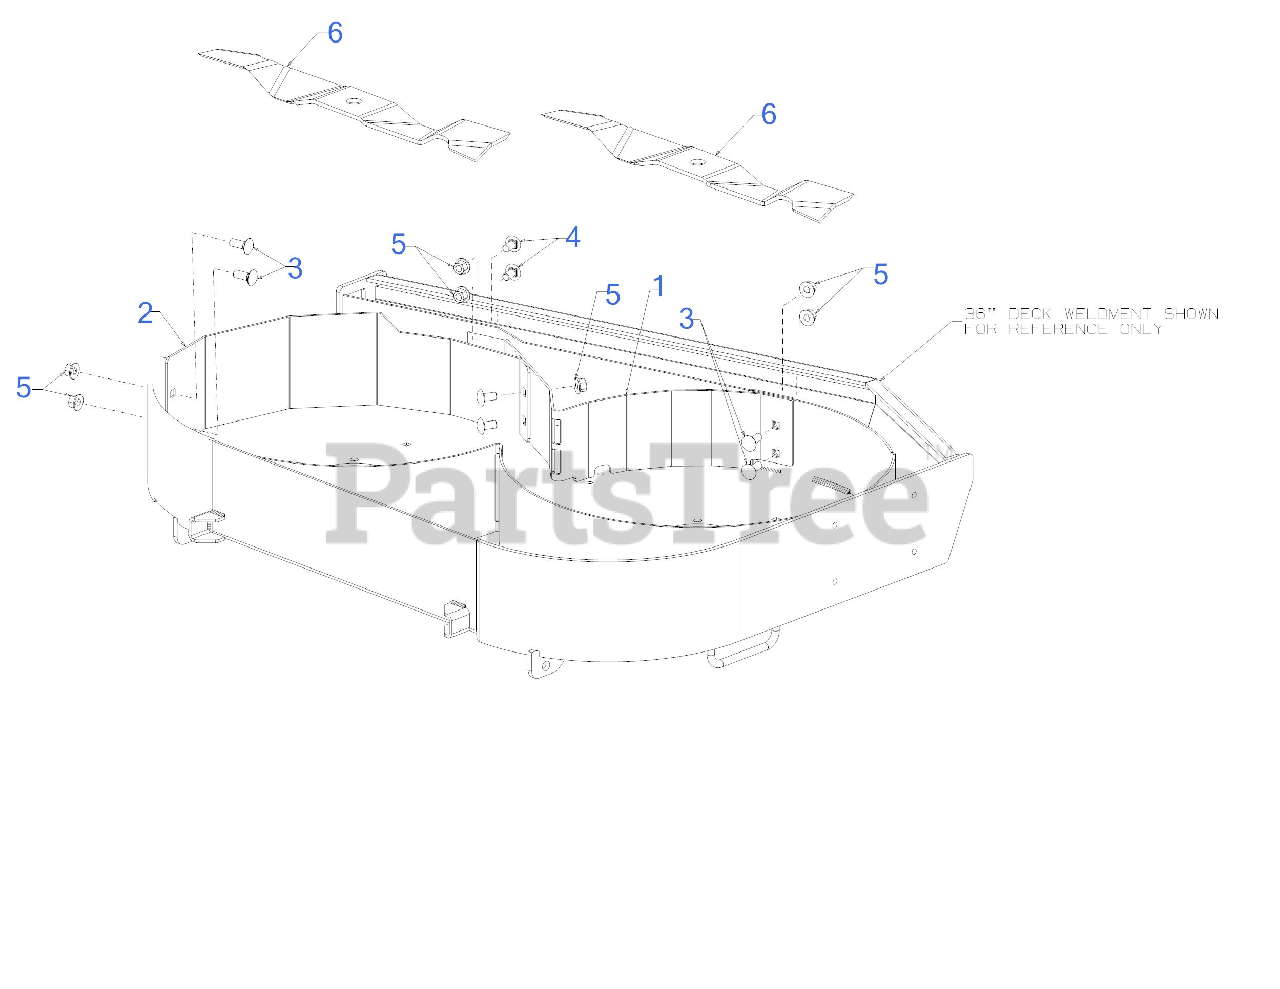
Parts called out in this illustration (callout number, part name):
1	36" MULCH BAFFLE (CENTER)
2	36" MULCH BAFFLE (RH)
3	CARRIAGE BOLT 3/8-16 x 1.00 GR5
4	CARRIAGE BOLT 3/8-16 x .75
5	NUT-CTRLCK FLG HEX
5	FLANGE LOCK NUT
6	MULCHING BLADE 18.5"
